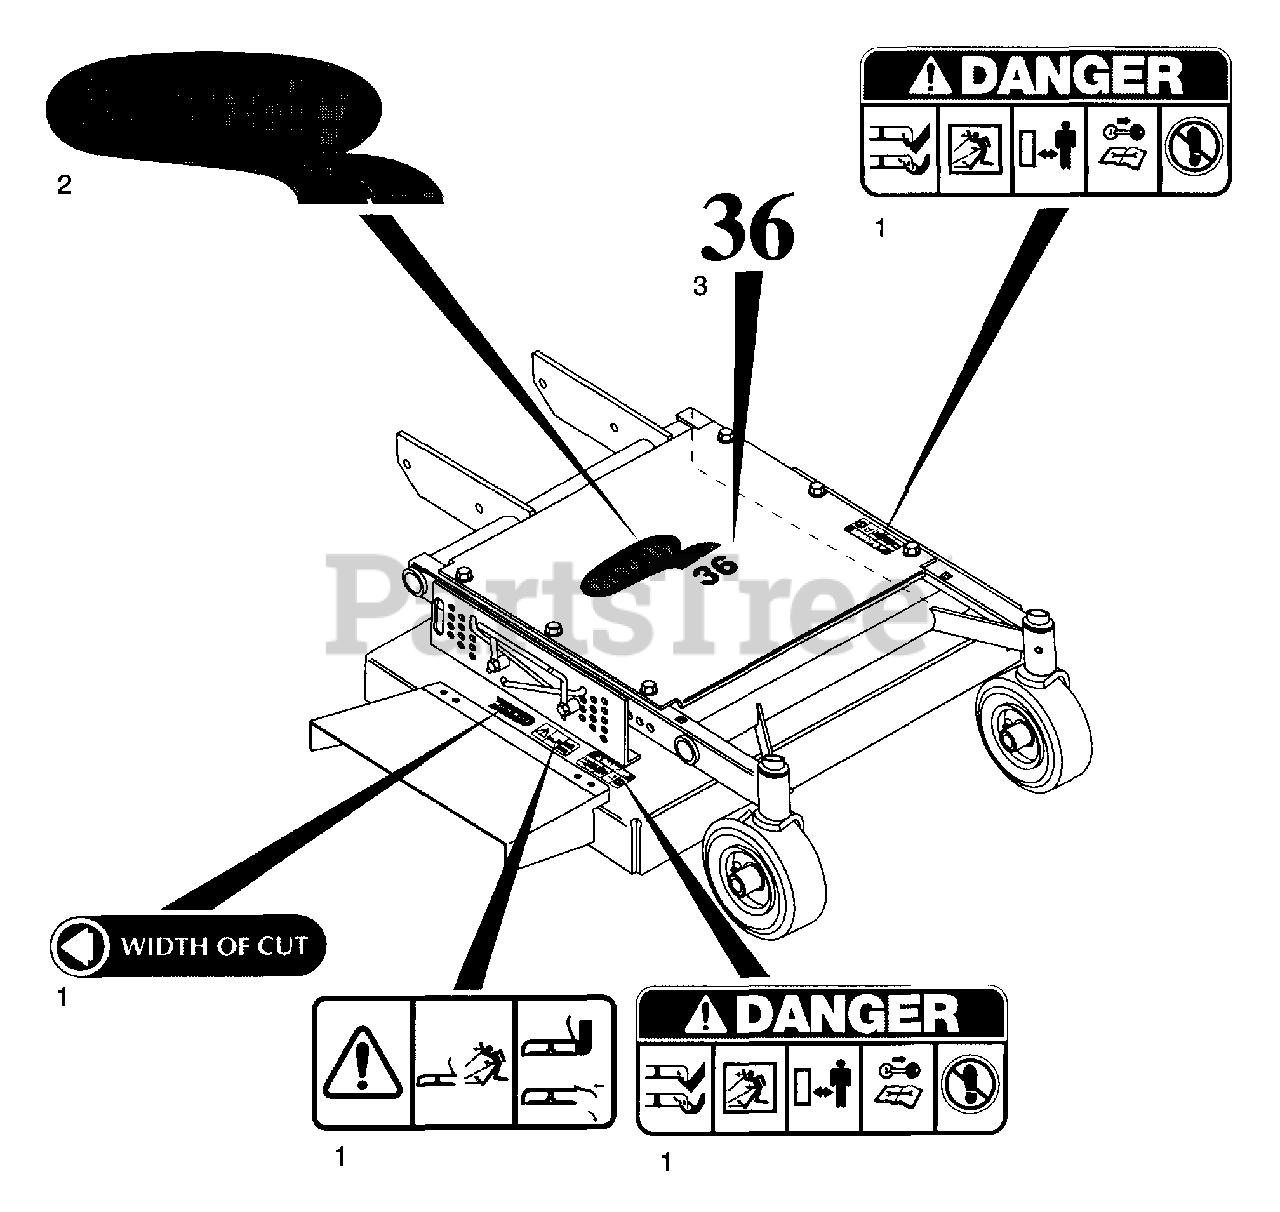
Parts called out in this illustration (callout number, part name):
1	Decal Set, Warning Protective
2	Decal-Gravely Logo
3	Decal-36"
